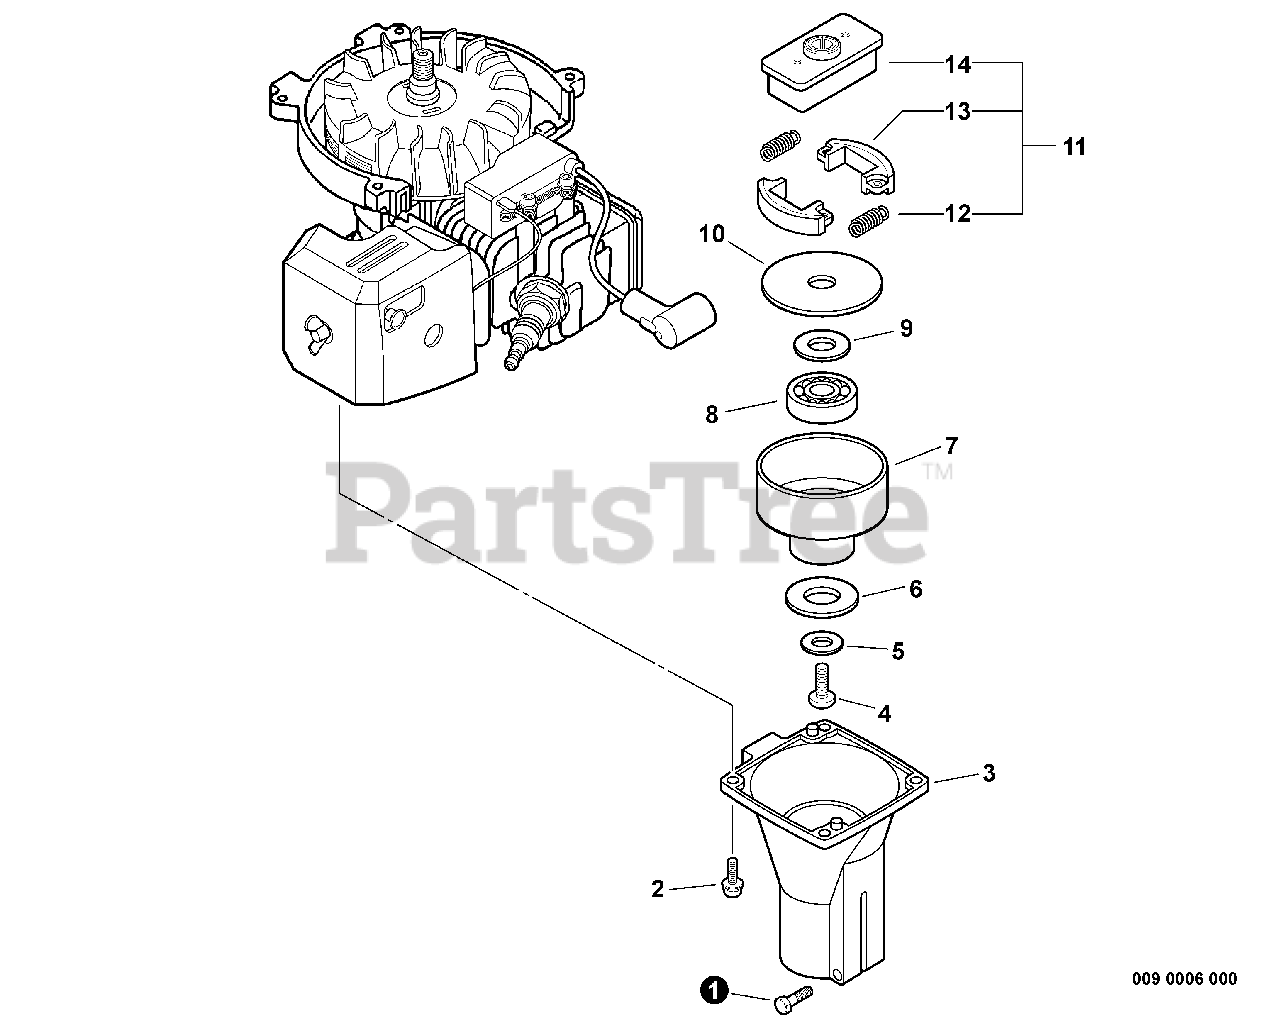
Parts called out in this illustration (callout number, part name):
1	BOLT 5
2	SCREW 4×18
3	CASE, CLUTCH
4	SCREW 6×12
5	WASHER, CLUTCH
7	DRUM, CLUTCH
8	BEARING, BALL 6000-2RLB
9	WASHER 10.5×18×1.6
10	PLATE, CLUTCH
11	CLUTCH ASSY
12	SPRING, CLUTCH
13	SHOE, CLUTCH
14	HUB, CLUTCH
